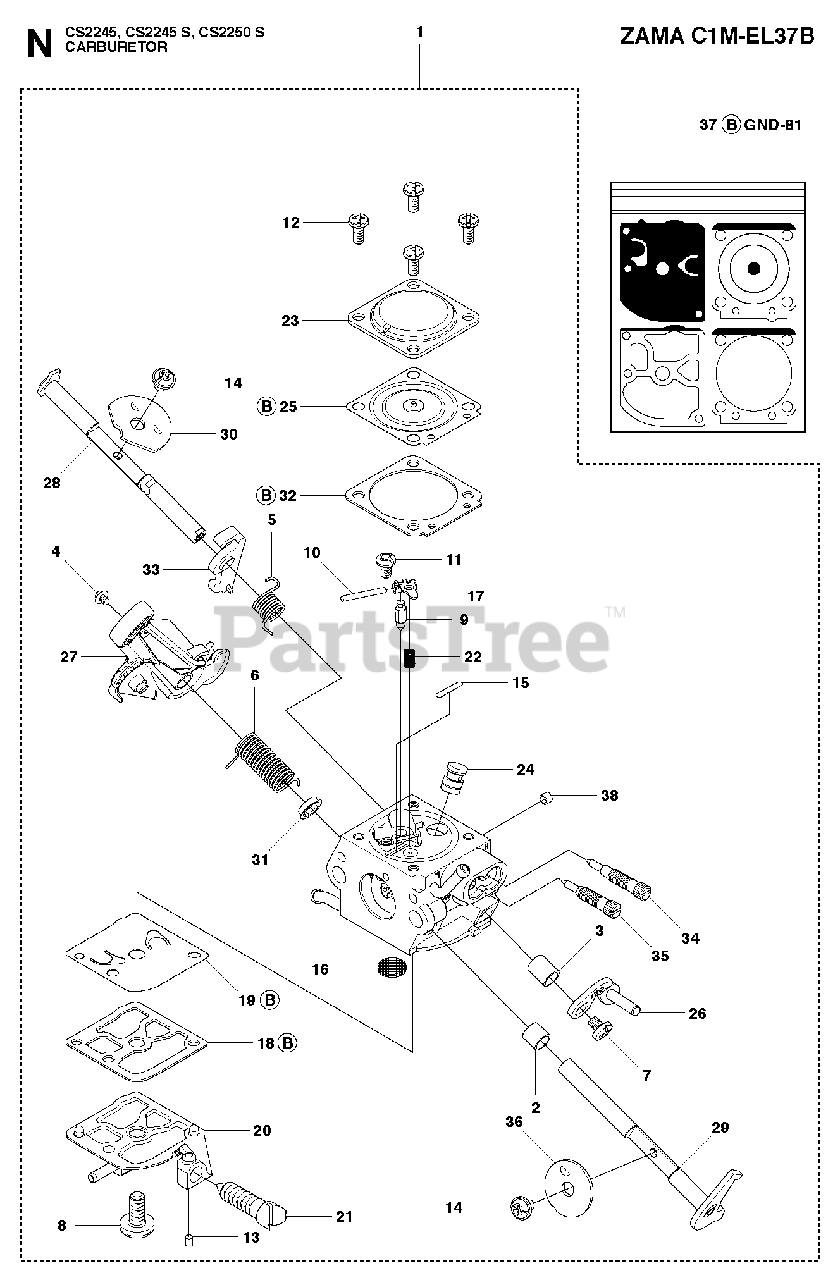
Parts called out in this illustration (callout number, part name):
1	CARBURETOR
2	COLLAR
3	COLLAR
4	SCREW
5	SPRING
6	SPRING
7	SCREW
8	SCREW
9	INLET NEEDLE
10	PIN FULCRUM
11	SCREW
12	SCREW
13	PLUG
14	SCREW
15	PLUG
16	STRAINER
17	LEVER
18	GASKET
19	PUMP DIAPHRAGM
20	COVER
21	SCREW
22	SPRING
23	COVER
24	JET
25	DIAPHRAGM
26	LEVER
27	THROTTLE LEVER
28	SHAFT ASSY
29	SHAFT ASSY
30	VALVE
31	COLLAR
32	GASKET
33	LEVER
34	SCREW
35	SCREW
36	VALVE
37	GASKET KIT
38	PLUG
